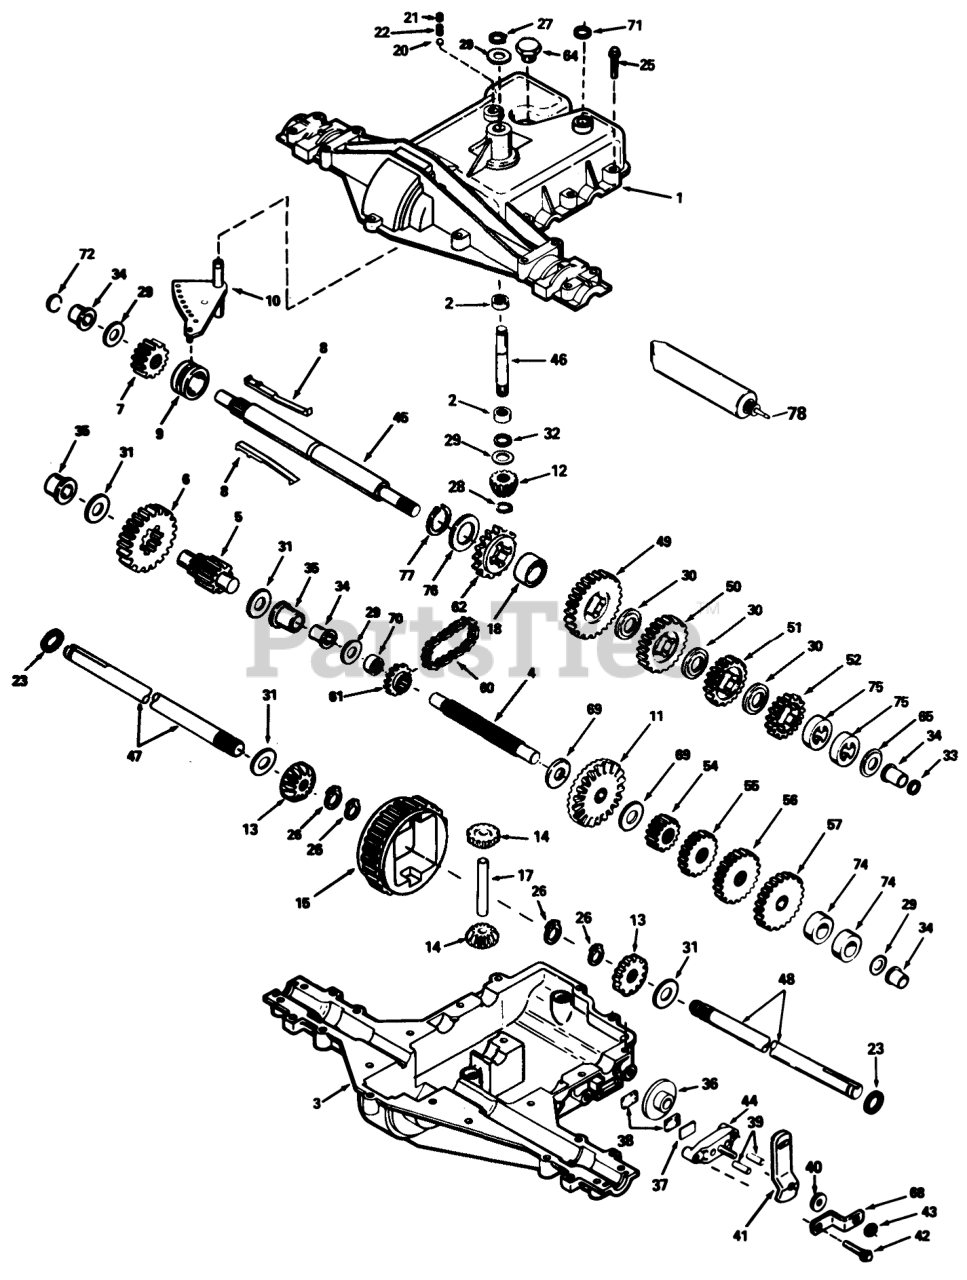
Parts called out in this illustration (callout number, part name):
1	Cover-Transaxle
2	Bearing-Needle
3	Case-Transaxle
4	Shaft-Counter
5	Output Shaft & Pinion Assy.
6	Gear-Output
7	Gear-Spur 15 Teeth
8	Key-Shifter
9	Shift Collar
10	Shift Rod & Fork Assy.
11	Gear-Bevel (42 teeth)
12	Bevel Pinion-Input
13	Gear Bevel
14	Gear Pinion
15	Gear-Ring
16	Drive Pin
18	Spacer
20	Ball-Steel
21	Screw-Set
22	Spring
23	Ring-Seal
25	Ring Set (.020 O S)
26	Retaining Ring (pkg of 2)
27	Ring-Snap
28	Ring-Retainer
29	Washer
30	Washer
31	Washer
32	O Ring
33	Ring-Square Cut
34	Bushing-Flange
35	Bushing-Flanged
36	Disk
37	Brake Pad Plate
38	Brake Pad
39	Dowel Pin
40	Washer
41	Lever-Brake
42	Ring Set (.020 O S)
43	Locknut
44	Nozzle-Carburetor
45	Shaft-Brake (4-keyed)
46	Shaft-Input
47	Axle (11-5/8" long)
48	Axle (16-1/4" long)
49	Gear-Spur (37 teeth)
50	Gear-Spur, 35 Teeth
51	Gear-Spur, 30 Teeth
52	Gear-Spur, 25 Teeth
53	Gear-Spur 20 teeth
54	Gear-Spur (12 teeth)
55	Gear-Spur, 15 Teeth
56	Gear-Spur, 20 Teeth
57	Gear-Spur, 25 Teeth
58	Gear-Spur (30 teeth)
60	Chain-Roller
61	Sprocket 10t
62	Sprocket (14 teeth)
64	Plug
65	Washer
68	Bracket
69	Washer
70	Spacer
71	Cut Seal-Square
72	Disk
74	Spacer
75	Spacer
76	Washer
77	Ring-Retaining
78	Grease 32 Oz
